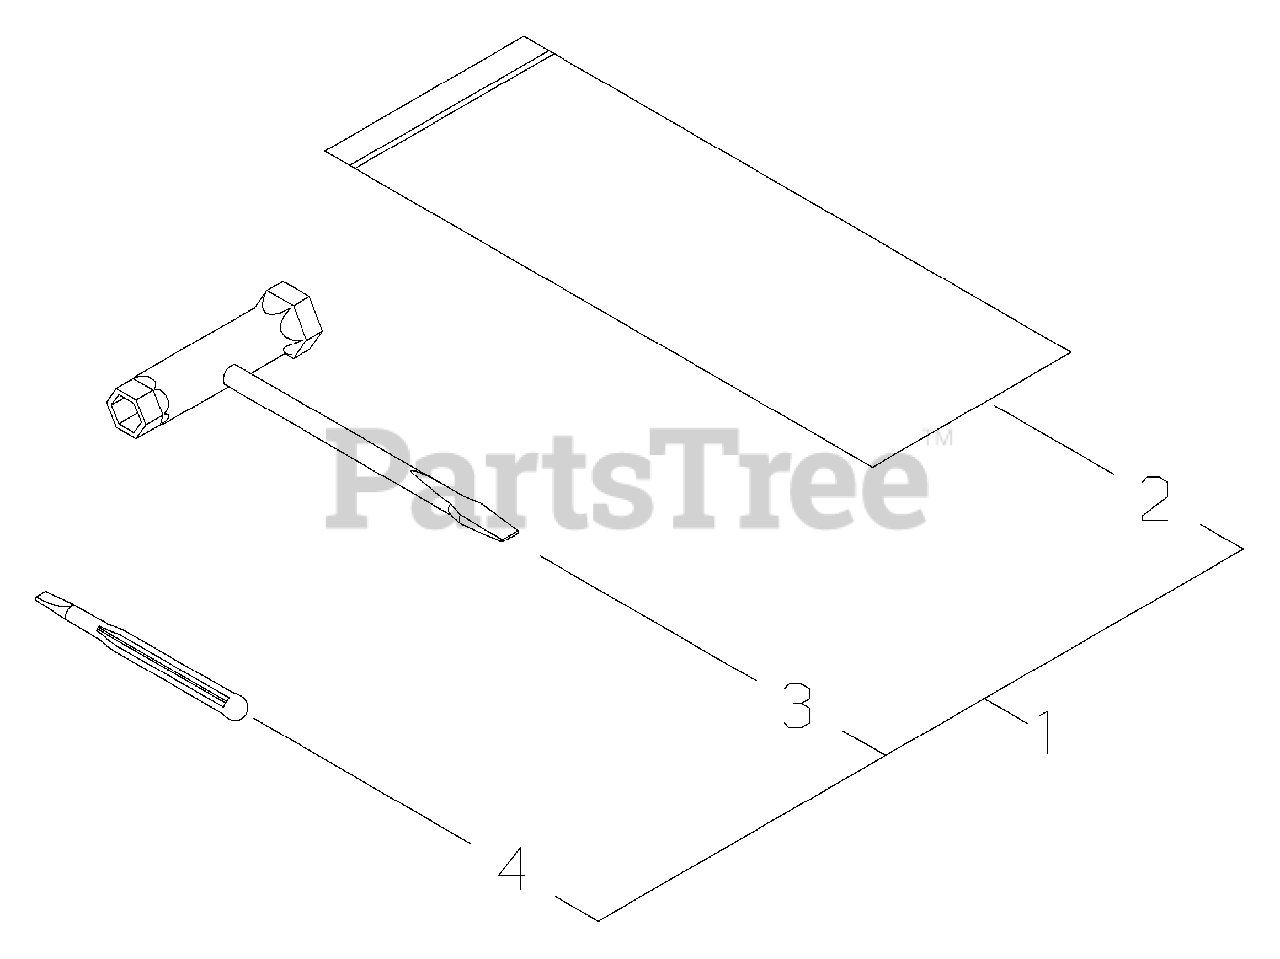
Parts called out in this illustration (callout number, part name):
1	TOOL KIT
2	BAG, TOOL
3	T-WRENCH - 13X19mm
4	SCREWDRIVER - PLASTIC
